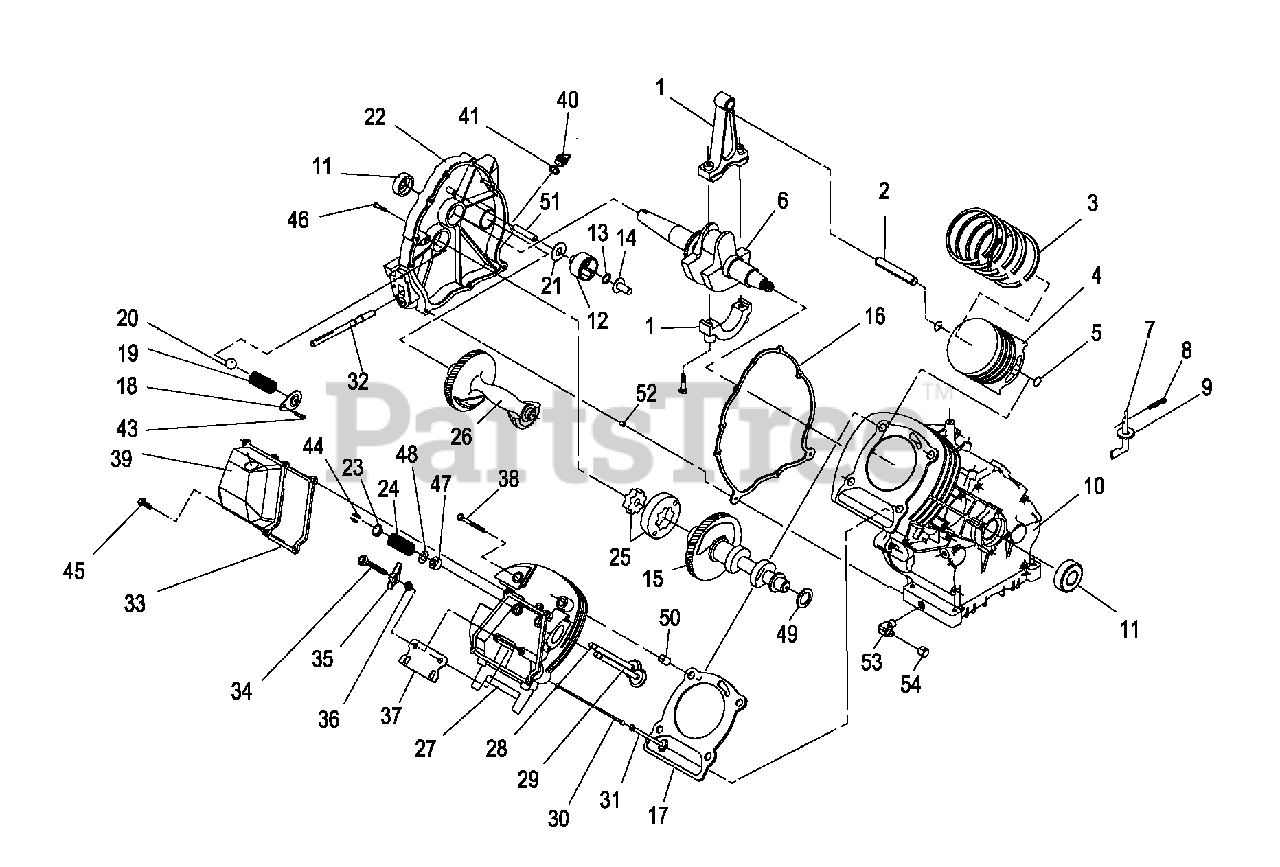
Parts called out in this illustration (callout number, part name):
1	ASSEMBLY, CONNECTING ROD
2	PIN, PISTON
3	RING SET, PISTON dia.90
4	PISTON, FLAT TOP
5	RETAINER, PISTON PIN 20
6	ASSEMBLY, CRANKSHAFT GH410 SMALL TAPER
7	ARM, GOVERNOR RC45
8	PIN COTTER "R" 0.59X1/4X1-1/8
9	WASHER, GOVERNOR ARM THRUST
10	CRANKCASE, SUBASSEMBLY WITH PLUGS GH410
11	SEAL, 35 I.D. CRANKSHAFT
12	ASSEMBLY, GOVERNOR GEAR
13	C-RING, GOVERNOR GEAR RETAINER
14	SPOOL, GOVERNOR- MACHINE
15	CAMSHAFT ASSEMBLY
16	GASKET , CRANKCASE
17	GASKET, HEAD 410
18	COVER, OIL PRESSURE RELIEF
19	SPRING, OIL RELIEF 360
20	BALL, DIA 11/32 PRESSURE RELIEF
21	WASHER, THRUST GOVERNOR GEAR
22	ASSEMBLY, COVER, GEAR TOP CHECK / FILL
23	RETAINER, VALVE SPRING
24	VALVE SPRING LF
25	SET,GEROTOR 12 THK
26	BALANCER
27	ASSEMBLY,CYLINDER HEAD SEATS & GUIDES
28	VALVE, EXHAUST
29	VALVE, INTAKE
30	PUSH ROD 174.9
31	TAPPET
32	ASSEMBLY, SCREEN OIL PICK-UP
33	GASKET, ROCKER COVER 410
34	STUD, D20 PIVOT BALL
35	ROCKER ARM
36	NUT, JAM (ROCKER ARM)
37	PLATE, PUSH ROD GUIDE
38	SCREW, HHFL M10-1.5 X 105
39	ASSEMBLY, ROCKER COVER BREATHER OHVI
40	PLUG, OIL FILL PLASTIC
41	O-RING 17.8 I.D. x 2.4
43	SCREW, TAPTITE M5-0.8 X 10 BP
44	KEEPER, VALVE SPRING
45	SCREW HHFCS M6-1 X 12
46	SCREW, HHFC M8-1.25 X 42
47	SEAL, VALVE STEM D7
48	WASHER, VALVE SPRING
49	WASHER, LARGE SPRING
50	SLEEVE, DOWEL PIN 14 DIA.
51	SHAFT, GOVERNOR RC55
52	SLEEVE, DOWEL PIN 12 DIA.
53	ELBOW ADAPTER, MIP X FLARE
54	CAP NUT, FLARE
